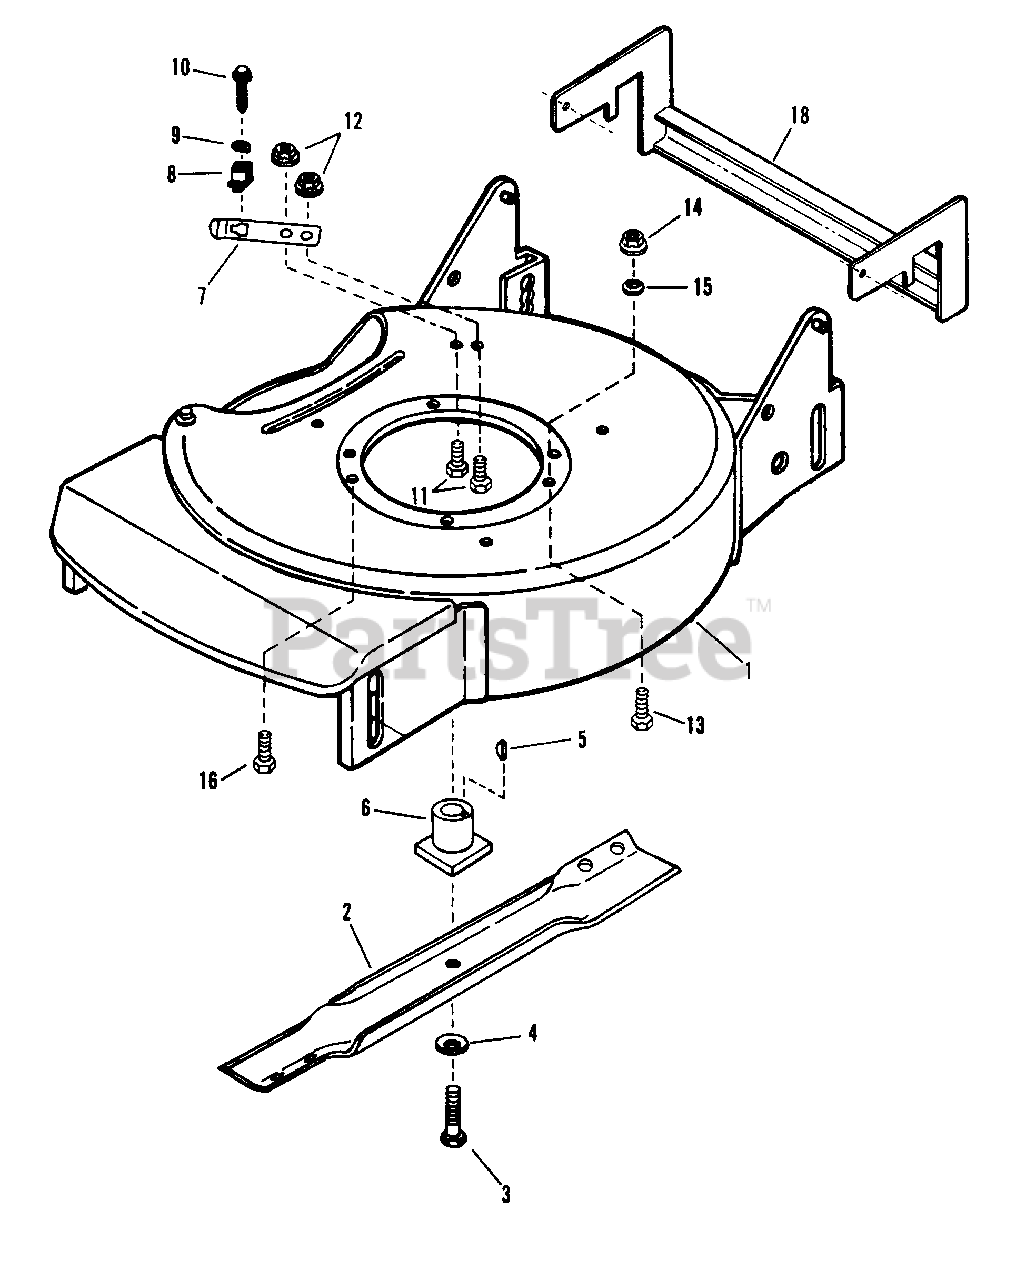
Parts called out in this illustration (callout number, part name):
1	WELDMENT, Deck (Tall Engine Mount)
2	BLADE, Cutter
3	SCREW, 3/8-24 x 2" Hex Head Cap, Grade 5
4	WASHER, Cone
5	KEY, Hi-Pro
6	HUB, Blade Drive
7	SPRING, Interlock
8	INSULATOR, Interlock
9	WASHER, #8 Tab
10	SCREW, #8-18 x 3/4" Sheet Metal
11	SCREW, 1/4-20 x 1/2" Hex Head Cap, Grade 5
12	NUT, 1/4-20 Hex Flange
13	SCREW, 5/16-18 x 5/8" Hex Head Cap, Grade 2
14	NUT, 5/16-18 Hex Flange Lock
15	RETAINER, 5/16" Bolt
16	SCREW, 3/8-16 x 1" Hex Washer Self-Tap
18	STRUCTURE, Fender
